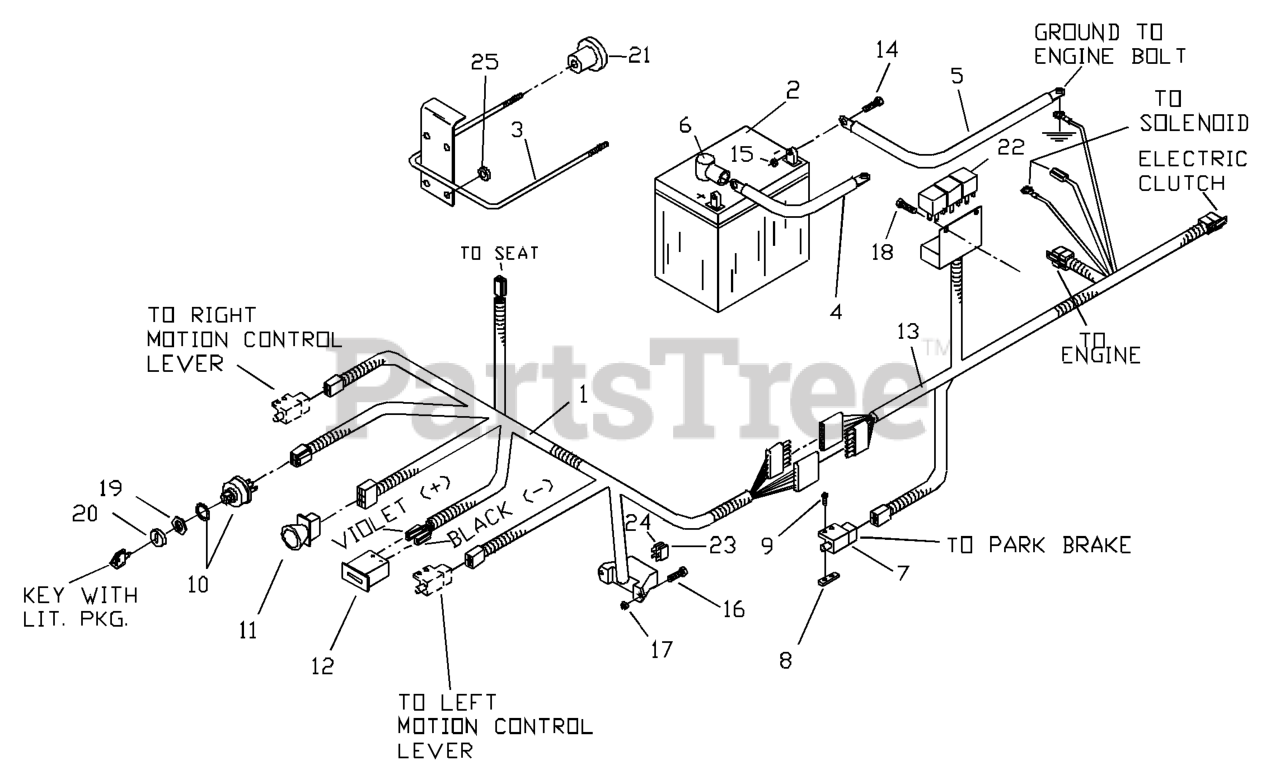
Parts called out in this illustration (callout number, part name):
1	CONSOLE HARNESS
2	BATTERY WET NOT SELLABLE
3	BATTERY HOLD DOWN
4	POST.CABLE LONG
5	CABLE-NEGATIVE
7	SWITCH, INTERLOCK
8	TAPPED PLATE
9	SCREW #10-24 X 5/8
10	IGNITION SWITCH KIT
11	RP.SWITCH, BLADE
12	HOUR METER
13	FRAMES HARNESS
14	HCS 5/16C X 3/4
15	NUT 5/16C CENTERLOCK
16	SCREW, #1--24 X 1/2 SLOTTED
17	NUT 10-24 NYLOC
18	SCREW #10 X 1/2 SELF TAPPING
19	DNO IGNITION NUT
20	CAP IGNITION NUT
23	FUSE, 7.5 AMP 32 VOLT ATO
24	FUSE, 20 AMP 32 VOLT ATO
25	GROMMET, BUMPER
